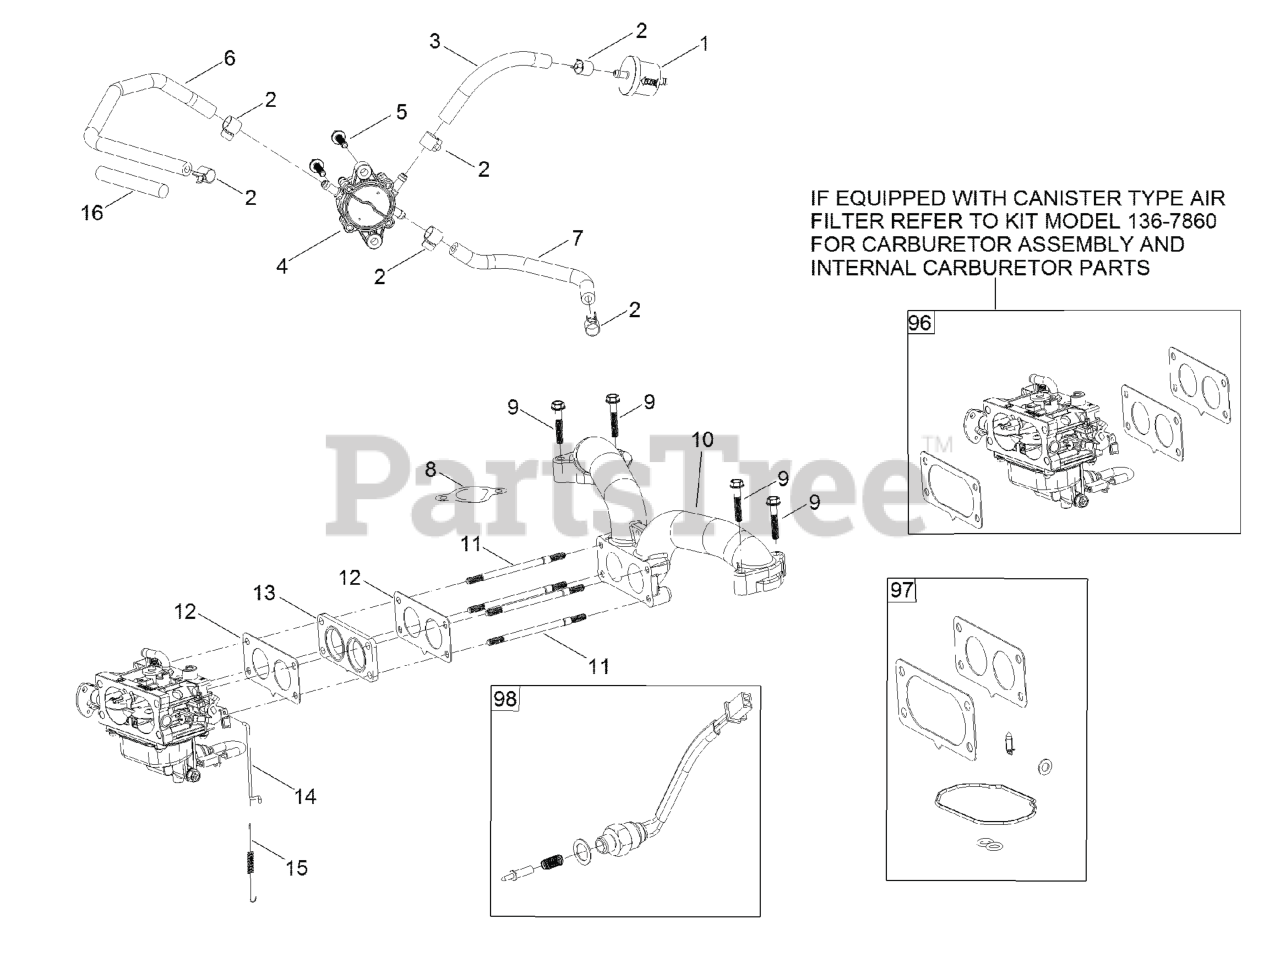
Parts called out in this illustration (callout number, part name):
1	FILTER-FUEL
2	CLAMP-FUEL LINE
3	LINE-FUEL
4	PUMP-FUEL
5	SCREW-HHF
6	HOSE-FUEL
7	HOSE-FUEL
8	GASKET-INTAKE
9	SCREW-HHF
10	MANIFOLD-INTAKE
12	GASKET-CARBURETOR
13	INSULATOR-CARBURETOR
14	LINKAGE-THROTTLE
15	SPRING-RETURN, THROTTLE
16	SLEEVE-FUEL LINE PROTECTO
96	CARBURETOR REPLACEMENT KI
97	CARBURETOR REPAIR KIT
98	SOLENOID KIT
